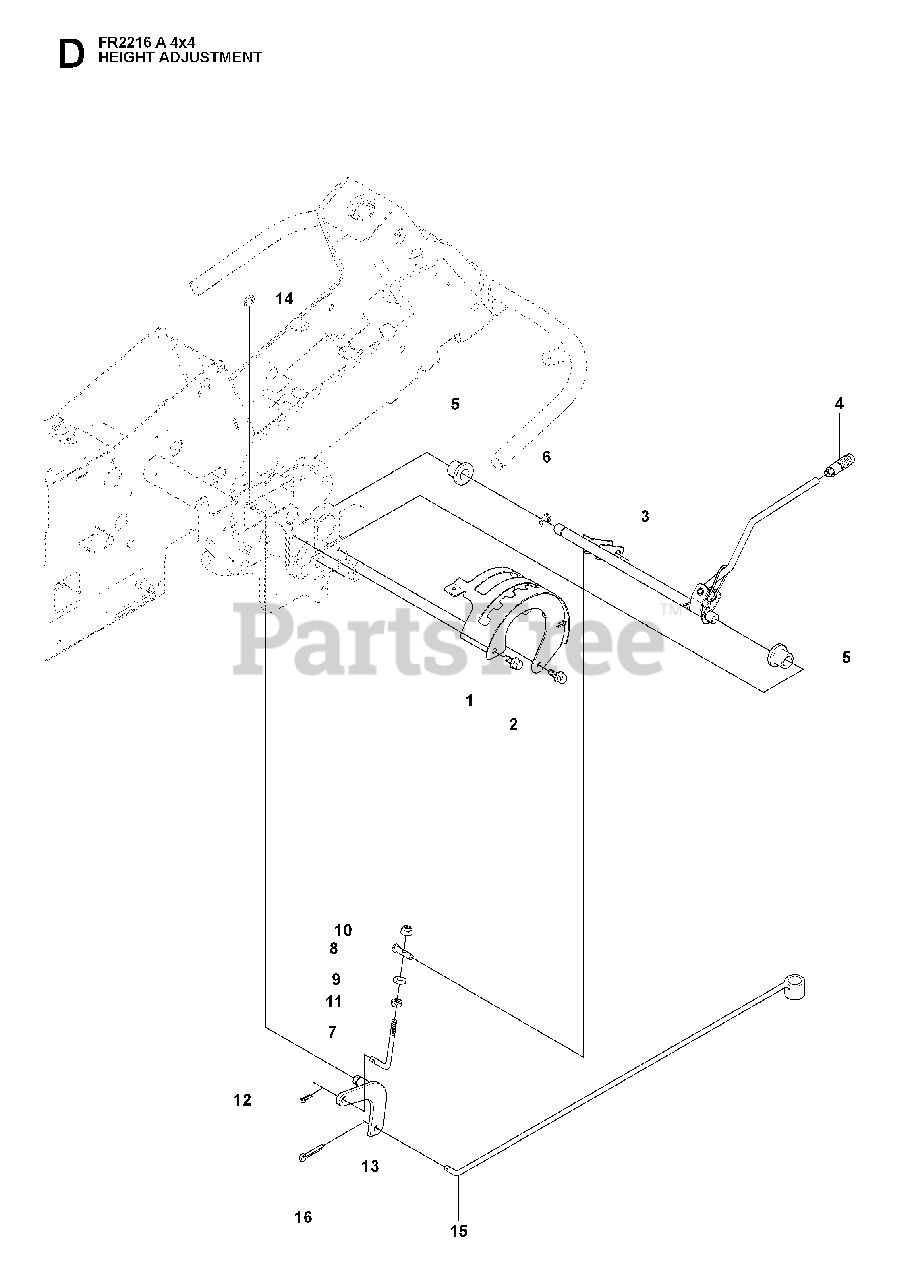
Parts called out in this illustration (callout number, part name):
4	GEAR STICK KNOB
5	BUSHING
9	WASHER
10	LOCKNUT M8
11	NUT
12	SPLIT PIN
14	RETAINING RING
15	CLUTCH ROD
16	SPLIT PIN
